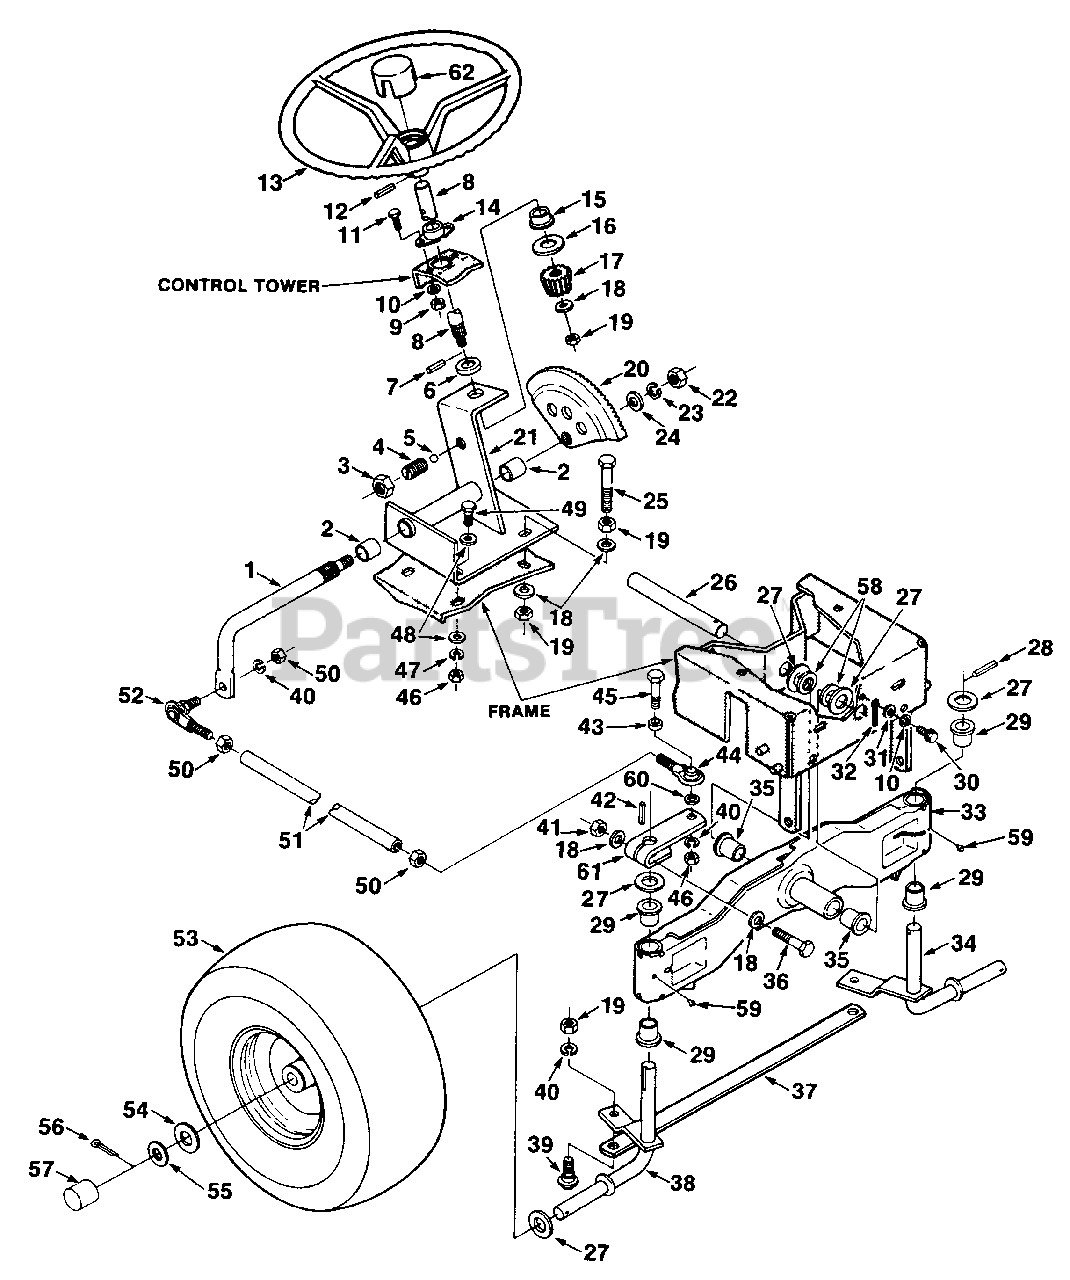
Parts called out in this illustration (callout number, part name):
1	ARM- Pitman
4	SPACER- Steering
5	BALL- .312 dia.
6	SPACER- Steering
7	PIN- Roll
8	SHAFT- Steering wheel
9	NUT- Hex 1/4-20
10	WASHER- Lock 1/4
11	SCREW
13	WHEEL- Steering
14	BEARING- Steering shaft
17	PINION- Steering
18	WASHER
20	STEERING- Gear
21	SUPPORT- Steering
29	BUSHING- Spindle
30	SCREW- 1/4-20 x 3/4
31	WASHER- Plain 1/4
32	PIN- Cotter
33	FRONT AXLE ASSY.
39	BOLT- Tie bar mounting
40	WASHER- 3/8 lock
41	NUT- Centerlock
43	SPACER- Ball Joint
44	BALL JOINT
45	SCREW
46	NUT
47	WASHER
48	WASHER
49	SCREW
52	BALL JOINT
53	RIM & TIRE ASSY.
55	WASHER-HT
59	FITTING- Grease
60	SPACER- Ball joint
61	ARM- Steering
62	CAP- Steering wheel
